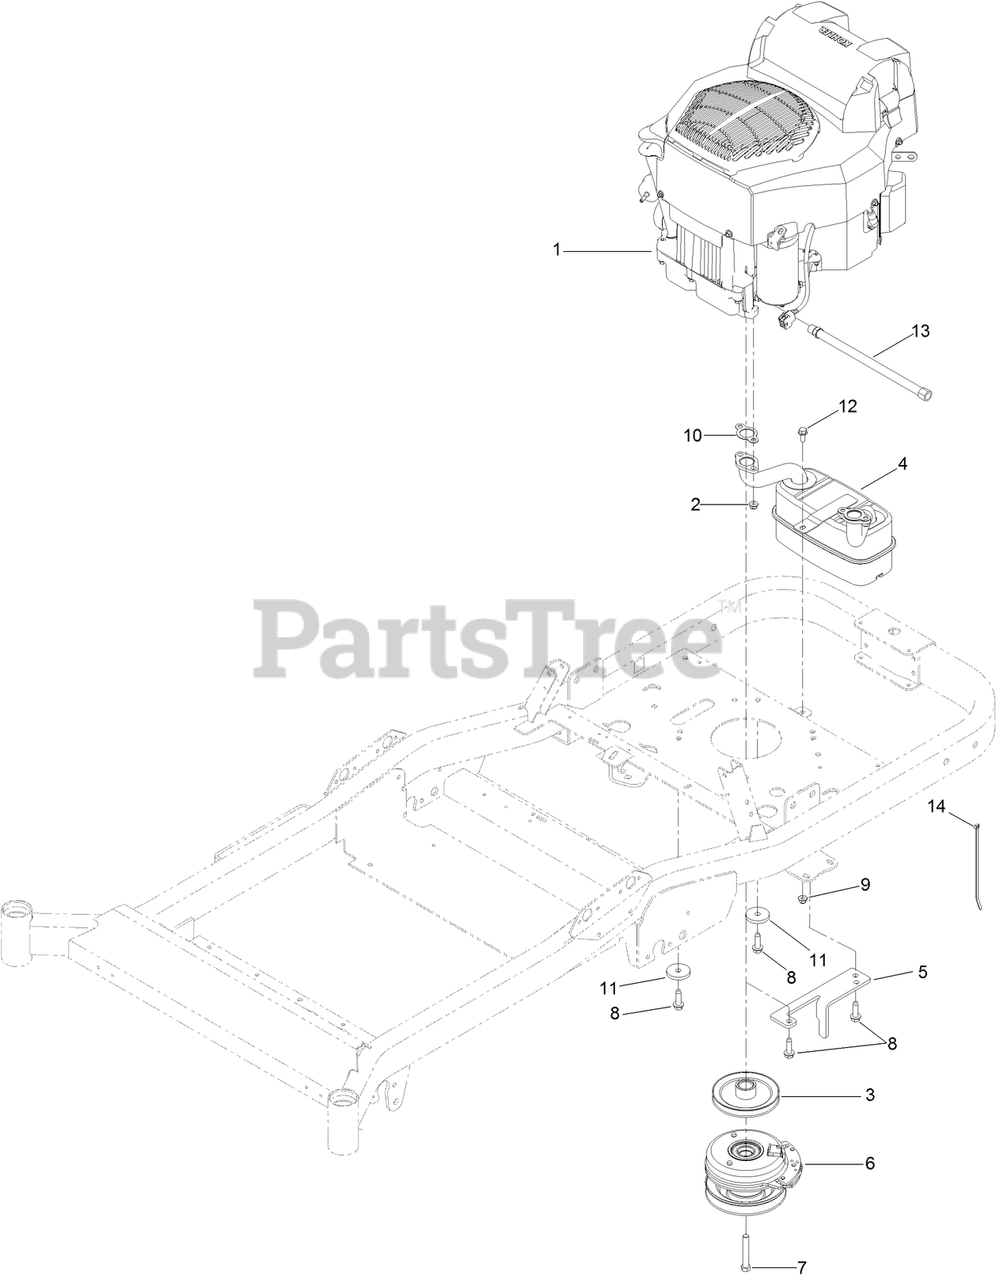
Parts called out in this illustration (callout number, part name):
2	NUT-LOCKING, EXHAUST
3	PULLEY-ENGINE
4	MUFFLER
5	BRACKET-STOP, PTO
6	CLUTCH-PTO
7	SCREW-HH
8	SCREW-THD
9	NUT-HF, NI
10	GASKET-EXHAUST
11	WASHER-PLAIN
12	SCREW-HHF
13	HOSE-DRAIN, OIL
14	TIE-CABLE
